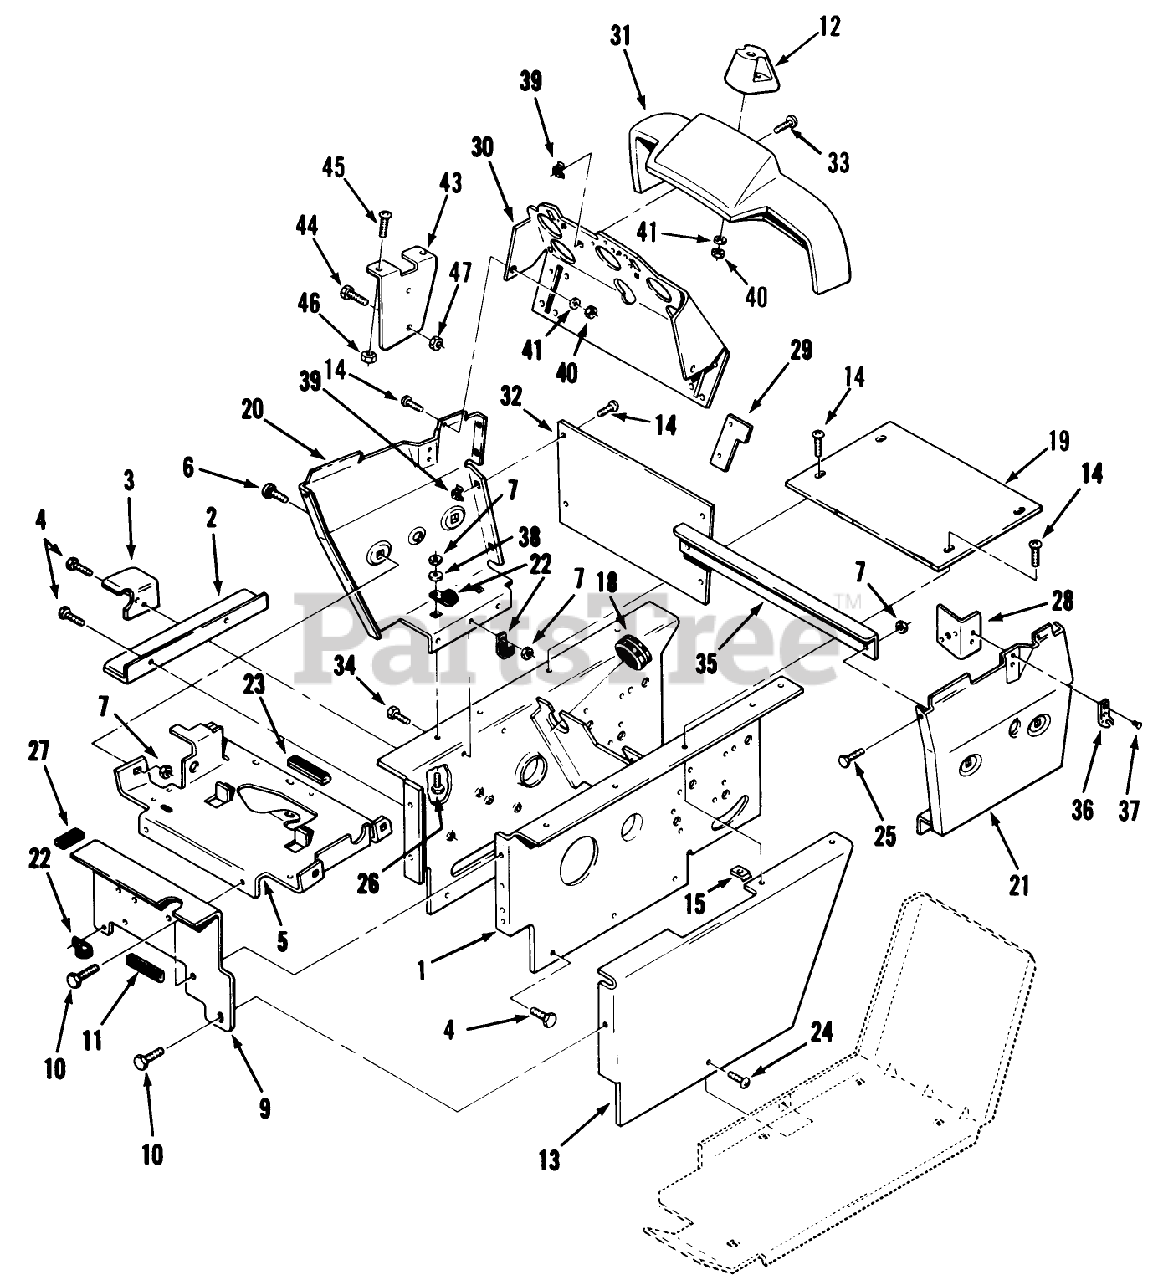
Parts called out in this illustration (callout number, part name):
2	ANGLE-BELT GUARD *B
4	SCREW
5	WLD-SUPPORT*B
7	NUT-LOCK, NI
10	SCREW
12	COVER-STEERING SHAFT
13	COVER-L.H. *R
14	SCREW-PPH
18	GROMMET
22	CLIP
26	CARRIAGE BOLT -4
28	BRACKET-SWITCH SU
29	STOP-CHOKE
35	STIFFENER-PANEL
36	KEEPER-LATCH
37	RIVET
38	WASHER-PLAIN
39	NUT-RETAINED
40	NUT-LOCK, NI
41	WASHER-FLAT
47	NUT-LOCK, NI
